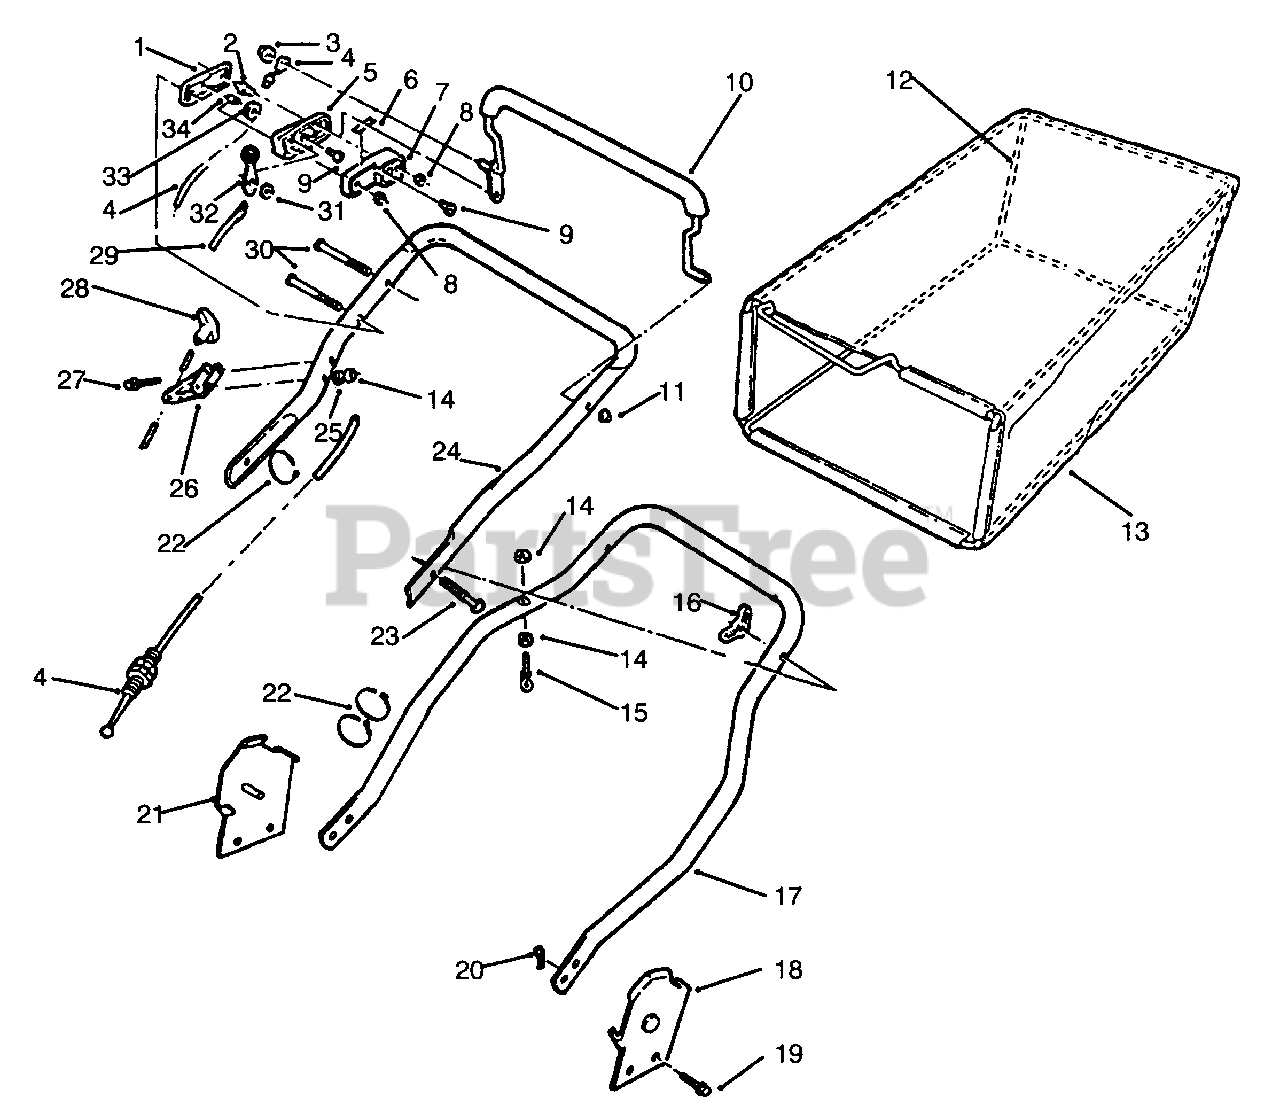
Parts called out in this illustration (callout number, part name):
1	Case-Outer, Control
3	Nut-Acorn, Cable to Bail
4	Cable-Engine Brake
5	Case-Center, Control
6	Decal-Throttle
7	Case-Inner, Control
8	Nut-Lock
9	Screw-Truss Head
10	Bail-Control, Eng. Brake
11	Nut-Push, Bail
12	Frame-Bag, Support
13	Assembly-Bag
14	Nut-Lock
15	Eyebolt
16	Nut-Wing
17	Handle-Bottom
18	Bracket-Handle, L.H.
19	Screw-Bracket, Handle
20	Pin-Hair
21	Bracket-Handle, R.H.
22	Strap Tie
24	Handle-Top
26	Guide-Rope
27	Screw-Truss Head
28	Handle-Starter
29	Cable-Throttle
30	Screw-Case, Control
31	Washer-Spring
32	Throttle & Knob
